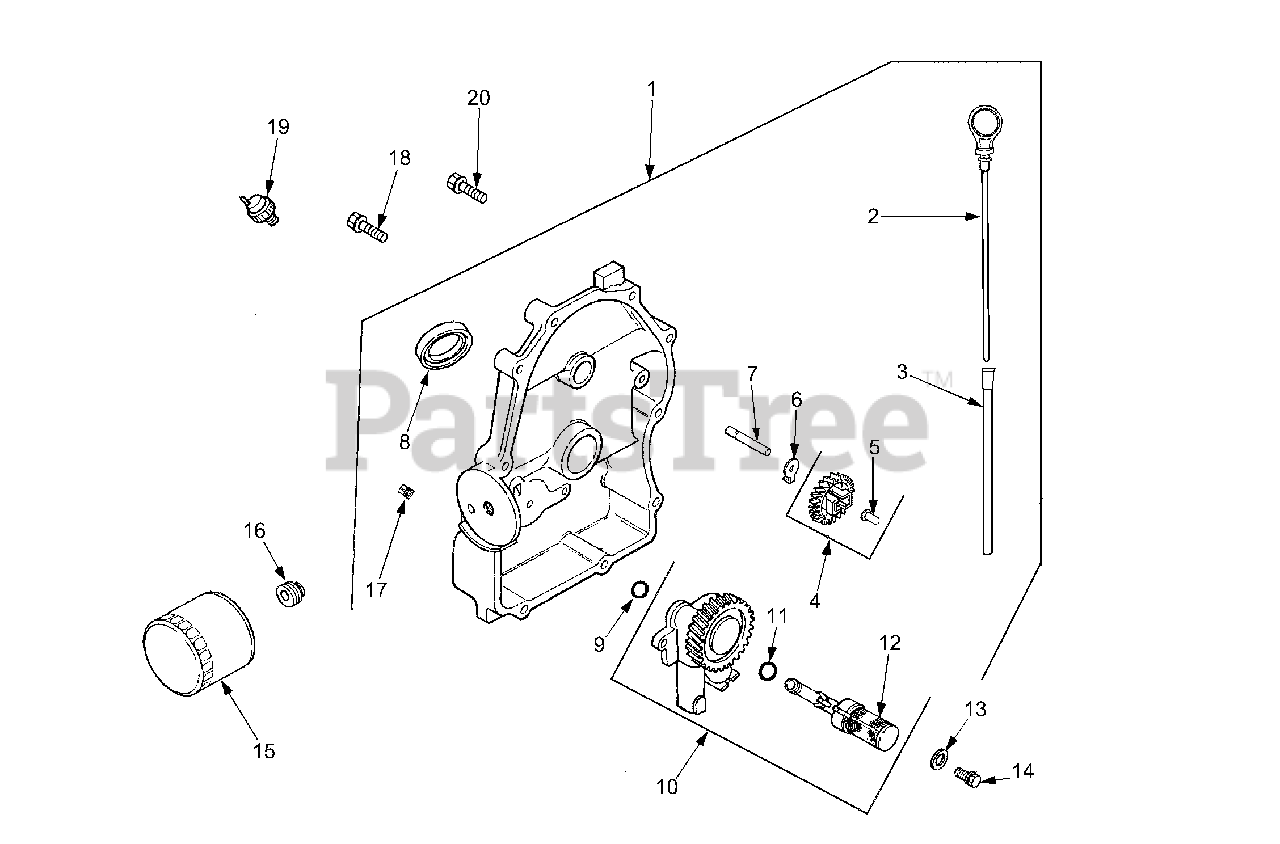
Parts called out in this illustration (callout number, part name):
1	Plate, Closure Assembly
3	Tube, Dipstick
4	Kit, Governor Gear
5	Pin, Governor Regulating
6	Tab, Locking
7	Shaft, Governor Gear
8	Seal, Oil (PTO End)
10	Oil Pump Assembly
11	O-Ring, Oil Pick-Up
12	Pick-Up, Oil
13	Washer, Plain
14	Screw, Hex Flange M6 x 1 x 25
15	Filter, Oil
16	Nipple, Oil Filter
17	Plug, Pipe 1/8"
18	Screw, Hex Flange M8 x 1.25 x 45
19	Switch, Pressure
20	Screw, Hex Flange M8 x 1.25 x 45
